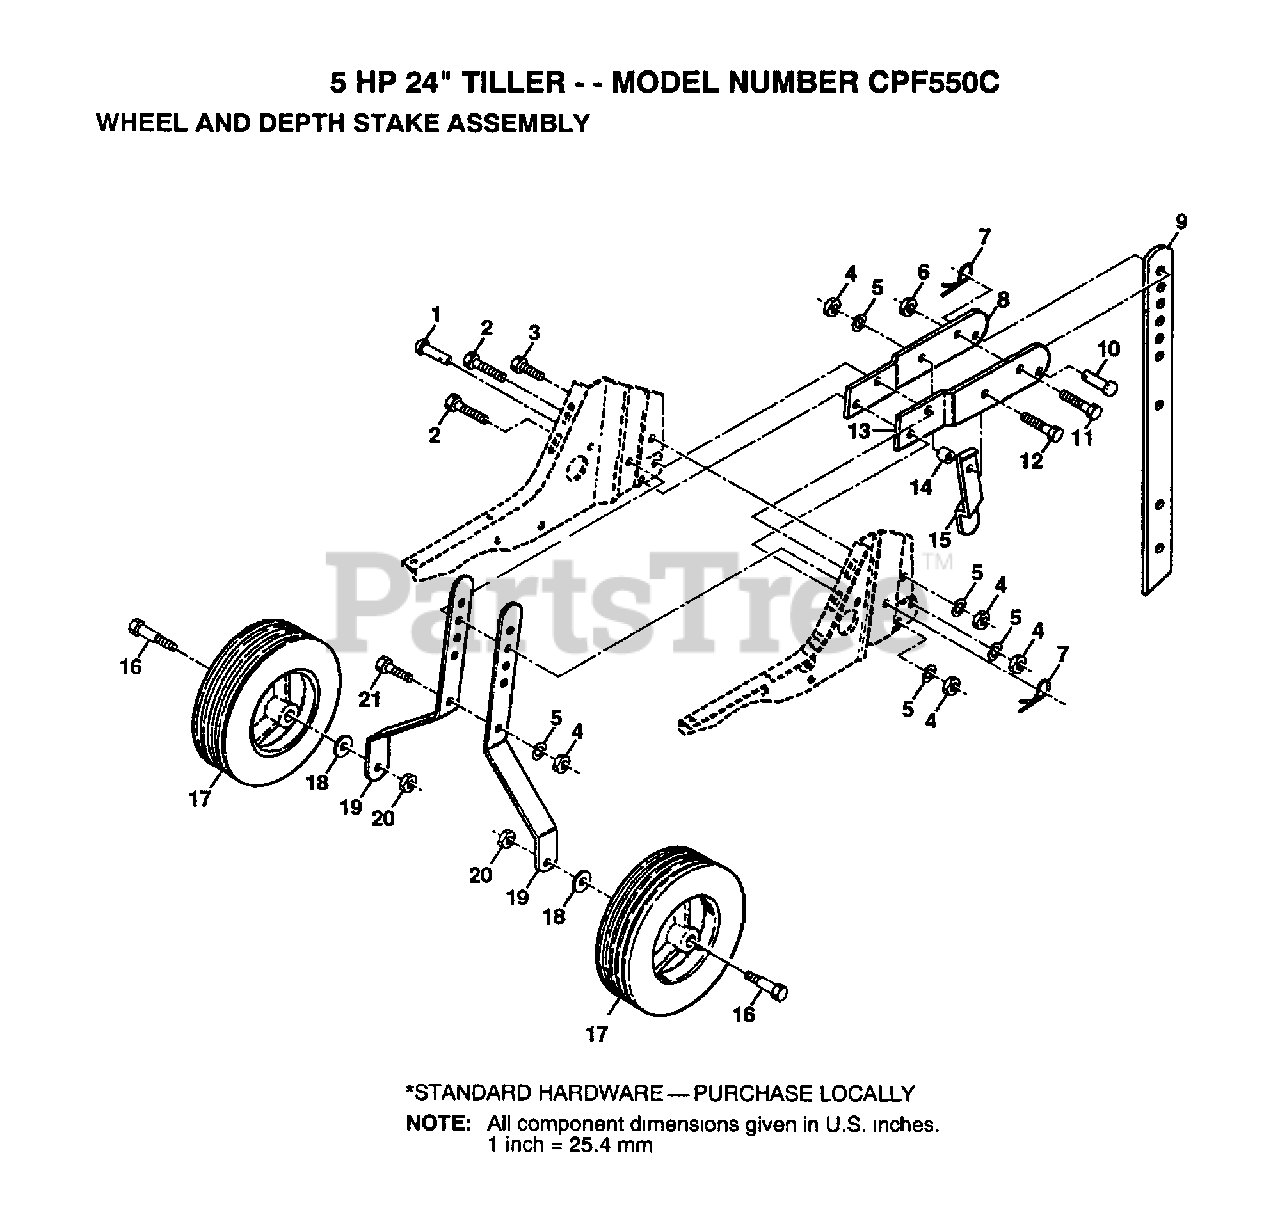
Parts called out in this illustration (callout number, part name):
1	DRILLED RIVET RT
3	BOLT
4	NUT.HEX.5/16-18
5	LOCKWASHER
6	GRIPCO NUT
7	SPRING.RETAINER
11	BOLT.3/8-24X1-1/2
12	BOLT.HEX.5/16-1.5
14	WASHER
15	STAKE SPRING TI
16	BOLT SHOULDER
18	WASHER
